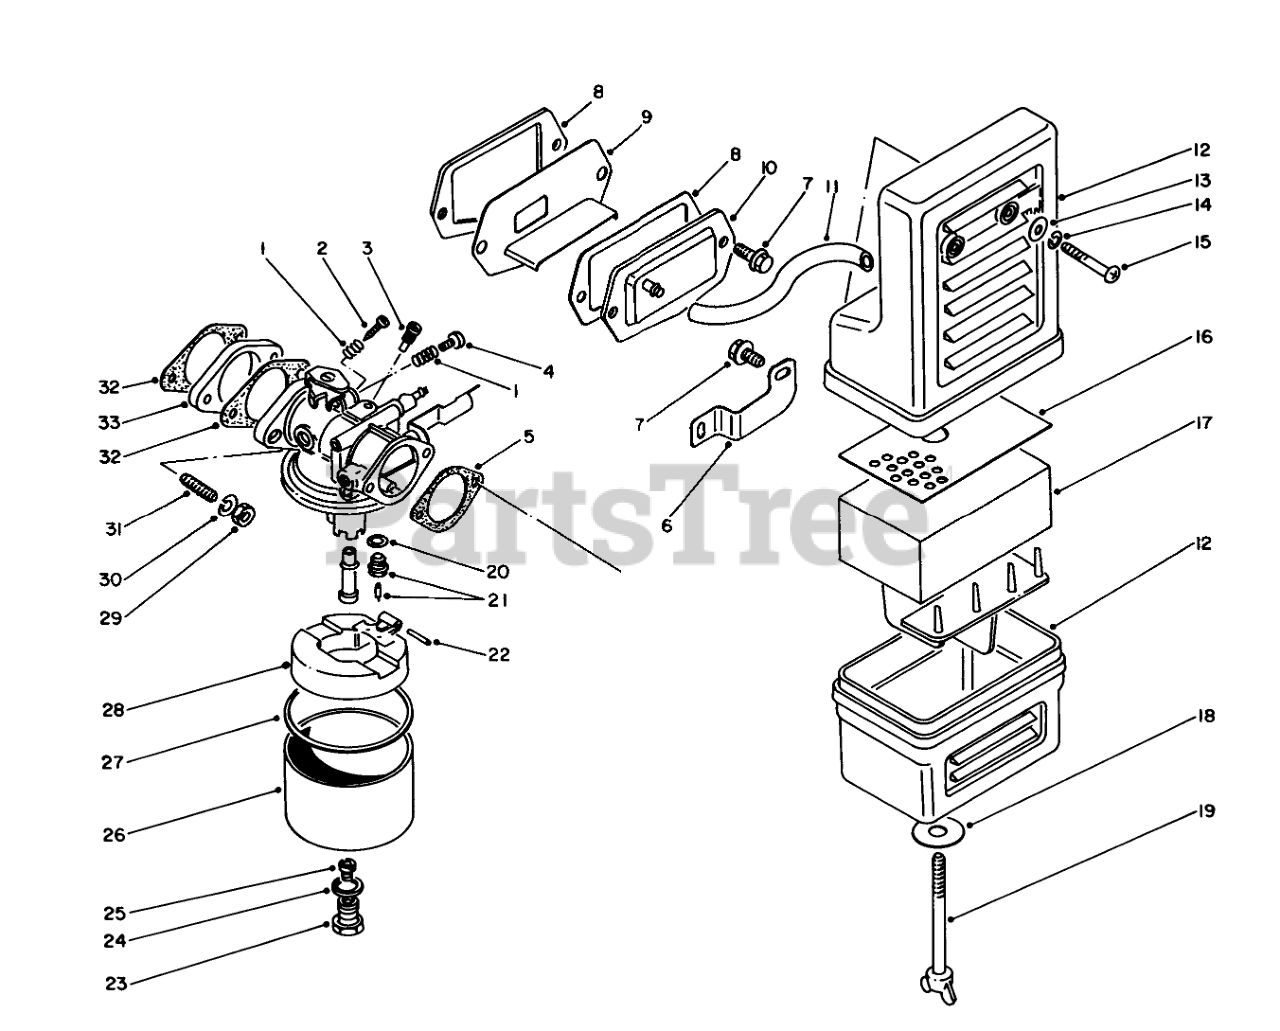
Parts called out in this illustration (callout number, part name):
1	Spring
2	ADJUSTER
3	Jet-Pilot (40)
4	Screw
5	AIR CLEANER GASKET
6	Bracket-Air Cleaner
8	Gasket
9	Reed Valve Assembly
10	Cap-Breather
12	Cleaner Assembly (Incl. Ref. #16-19)
13	WASHER
14	Washer
15	SCREW
16	Holder
17	FILTER
18	WASHER
19	Bolt-Wing
20	GASKET
21	NEEDLE VALVE
24	Gasket
25	Jet-Main (72-5)
26	Carburetor Assembly (Incl. Ref. #20-25 & 27-28)
27	GASKET
28	Float
30	Lockwasher
31	Bolt-Stud
32	Gasket
33	INSULATOR
